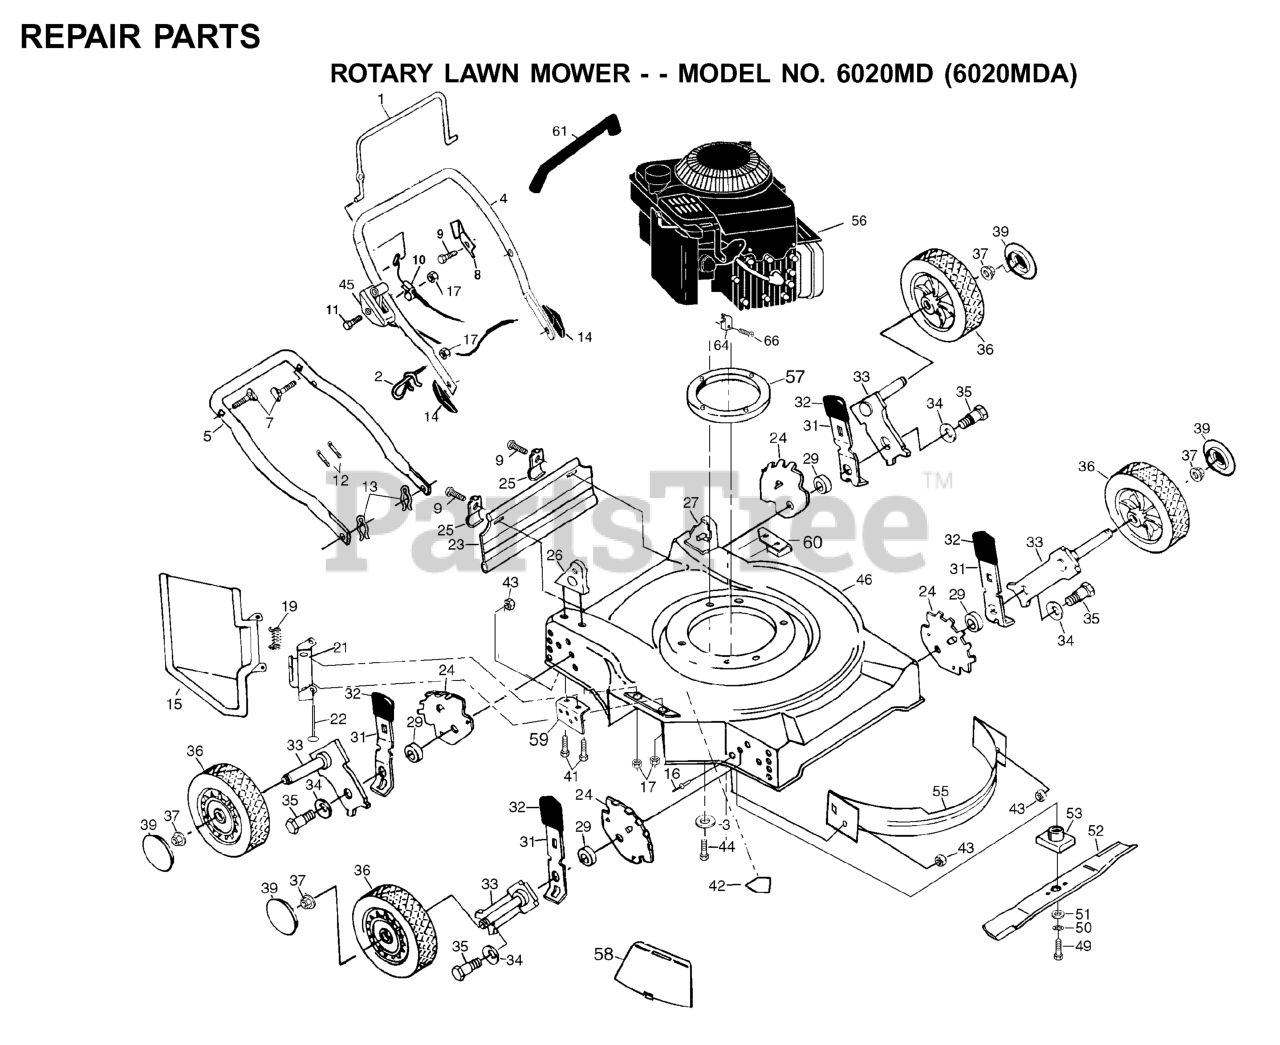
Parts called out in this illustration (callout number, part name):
4	UPPER HANDLE
5	REPL BY 532 15 70-82
7	HANDLE BOLT
8	BRACKET UPSTOP
9	TAPPING SCREW
10	CABLE.MZR.51.RT.SP./PU.
11	SCREW 1/4-20 X 2.12
12	TIE GUIDE
13	HAIRPIN COTTER
14	NUT WING PM
15	DISCHARGE GUARD
16	RIVET BLIND
17	NUT
21	BRACKET PM
22	ROD.HINGE.COMBI-C
23	REAR SKIRT
24	WHEEL ADJUST BRACKET
25	BRACKET DEFL PM
26	HANDLE BRACKET ASM. RH
27	HANDLE BRACKET ASM. LH
29	RP SPACER HT ADJ
31	SELECTOR SPRING
33	AXLE, REAR
34	WASHER.BELLEVILLE (3 2 LB)
35	BOLT
37	HEX FLANGE LOCKNT
39	CAP.HUB.BLACK.WALK
41	SCREW.5/16-18X3/4
42	DECAL HYT
43	LOCKNUT PM
45	THROTTLE CONTROL
49	SCREW, HEX HD 3/8-24 X 1-3/8
50	LOCKWASHER
51	WASHER,HARDEN
52	BLADE.20.MULCH.(50DK,6020MD)
53	BLADE ADAPTOR
55	REPL BY 532 14 60-26
58	REPL BY 532 12 54-20
59	REPL BY 532 12 52-05
61	GRIP.HANDLE.FOAM
64	CABLE CLAMP(ENGINE)
66	SCREW.HEX.HEAD.WASHER.10-16
